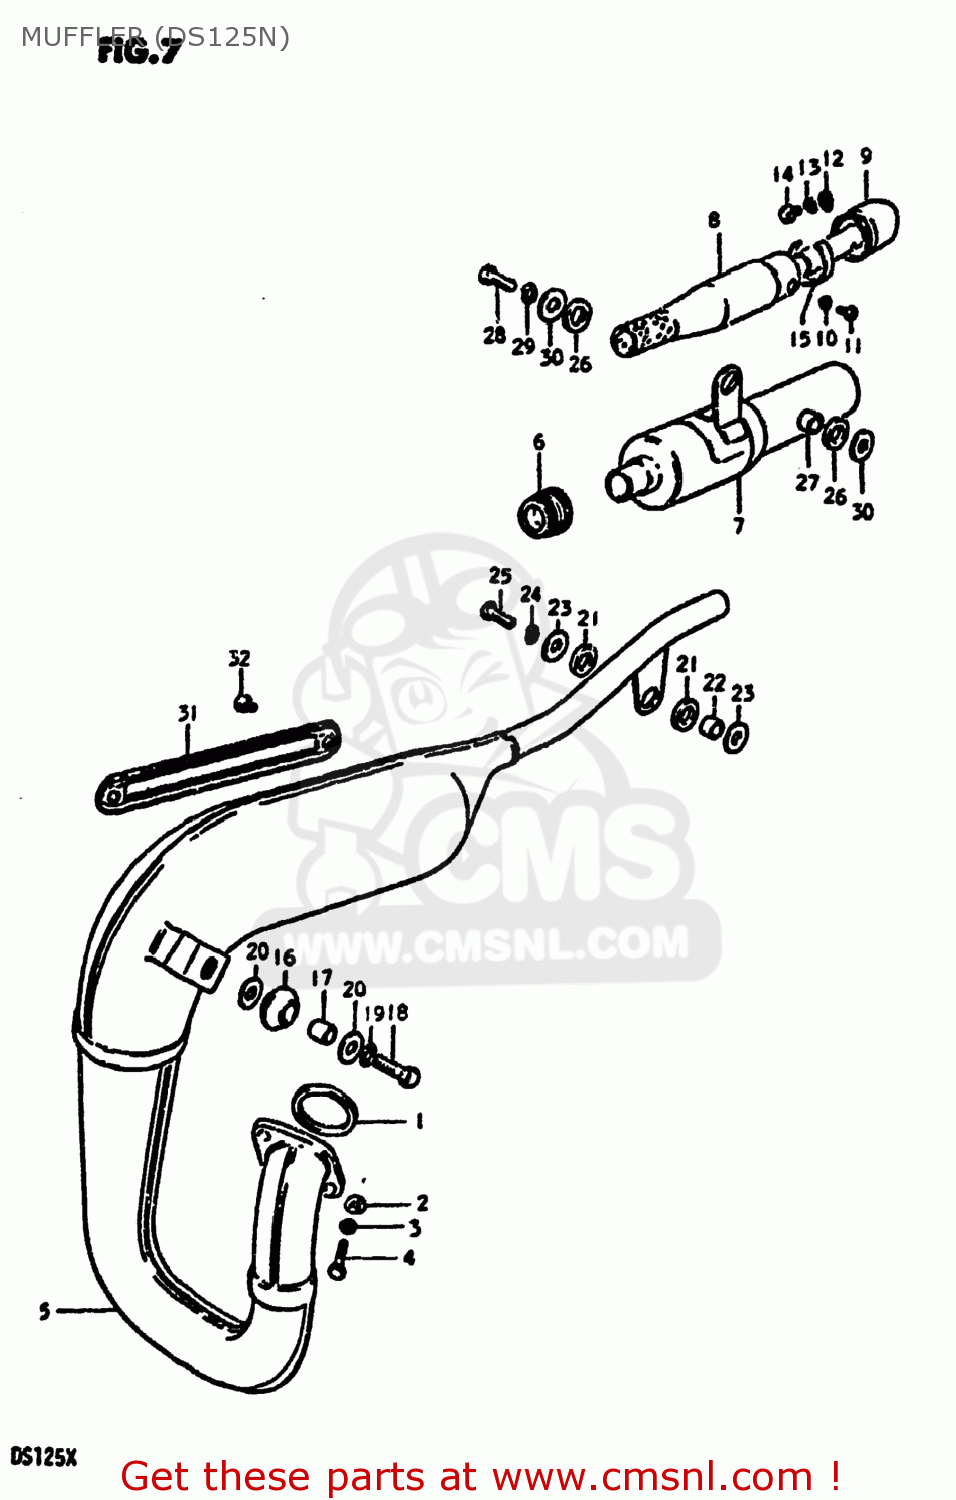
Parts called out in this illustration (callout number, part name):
1	GASKET,EXHAUST PIPE (NAS)
2	WASHER
3	LOCK WASHER
4	SCREW
5	BODY,MUFFLER
6	CONNECTOR,MUFFLER
7	MUFFLER ASSEMBLY
8	ARRESTER,SPARK
9	TUBE,MUFFLER CLEAN OUT
10	LOCK WASHER
11	SCREW
12	WASHER
13	LOCK WASHER
14	SCREW(6X8)
15	BAND,SPARK ARRESTER
16	DAMPER,MUFFLER,FR
17	SPACER (8X12X15)
18	BOLT
19	LOCK WASHER
20	WASHER (8.7X22X2)
21	CUSHION
22	SPACER (8.6X13.8X9.8)
23	WASHER
24	LOCK WASHER
25	BOLT
26	CUSHION
27	SPACER (8.6X13.8X9)
28	BOLT
29	LOCK WASHER
30	WASHER
31	COVER,MUFFLER
32	SCREW
